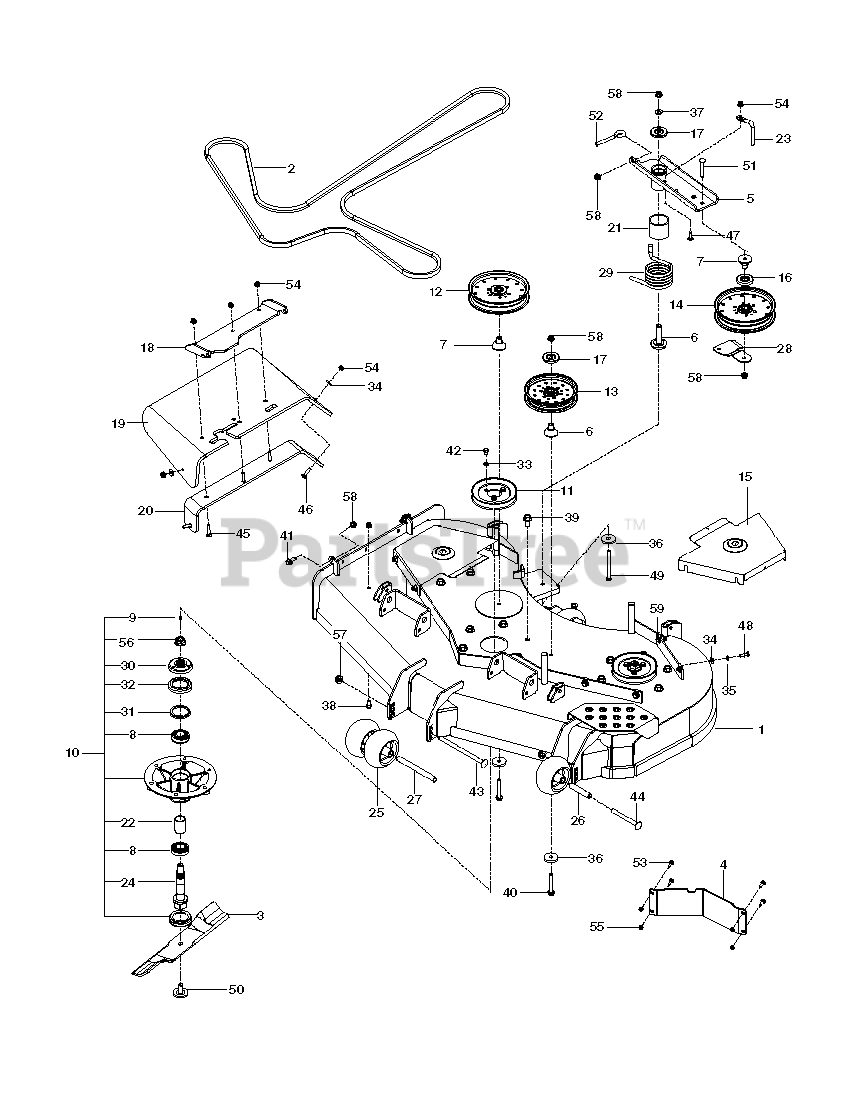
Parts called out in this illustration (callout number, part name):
1	CHUTE.WELDMENT.SNOW.ORANGE
2	DEFLECTOR.WELDMENT.PNT.ORANGE
3	RP.CONTROL.ASM.DEFLECTOR.SNOW
4	SEAL.DEFLECTOR
5	KNOB.OVERMOLD.DS.HUSQVARNA/BLK
6	RIVET BLIND
7	SCREW #10-24 X 5/8
8	SHIELD.SNOW.CHUTE
9	STRAP.SHEILD.RETAINER
10	BOLT, SHOULDER
11	NUT.HEX.FLANGE.1/4
12	BOLT
13	NUT.LOCK.5/16-18
14	SPRING.DEFLECTOR.REM.CHUTE
15	RP CNTRL.HEAD.ASSEM.DEFLECTOR
16	RB SERVICE.CHUTE.DEF.CBL.BLK
